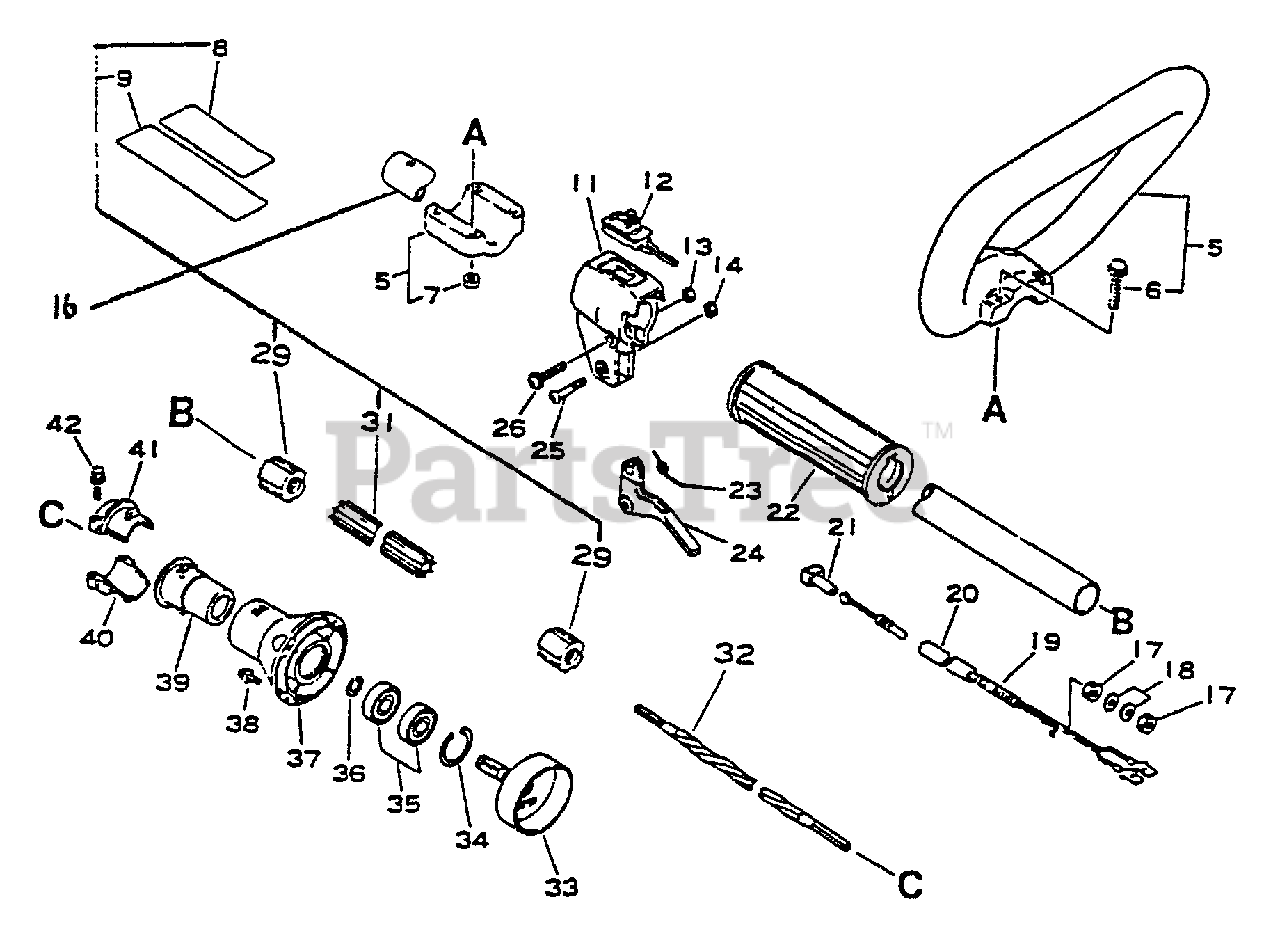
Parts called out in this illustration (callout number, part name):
5	LOOP HANDLE ASSY
6	NUT M5
7	SCREW - 6×35
8	LABEL - CAUTION
9	LABEL - CAUTION
11	BRACKET, THROTTLE CONTROL
12	IGNITION SWITCH ASSY
13	NUT M5
14	LOCKNUT - 5
16	MAIN PIPE ASSY
18	WASHER, SPRING 6
19	CABLE, THROTTLE
21	GUIDE, CABLE
22	GRIP, HANDLE
23	SPRING, THROTTLE
24	TRIGGER, THROTTLE
26	SCREW 5×30
31	LINER, FLEXIBLE 21.6×1420
32	DRIVESHAFT - FLEXIBLE L= 1522
33	DRUM, CLUTCH
34	RING, SNAP Ø25
35	BEARING, BALL 6001
36	RING, RETAINING - 12
37	CASE, CLUTCH
38	SCREW 5×16
41	HOLDER, MAIN PIPE - UPPER
42	BOLT - 5×25
